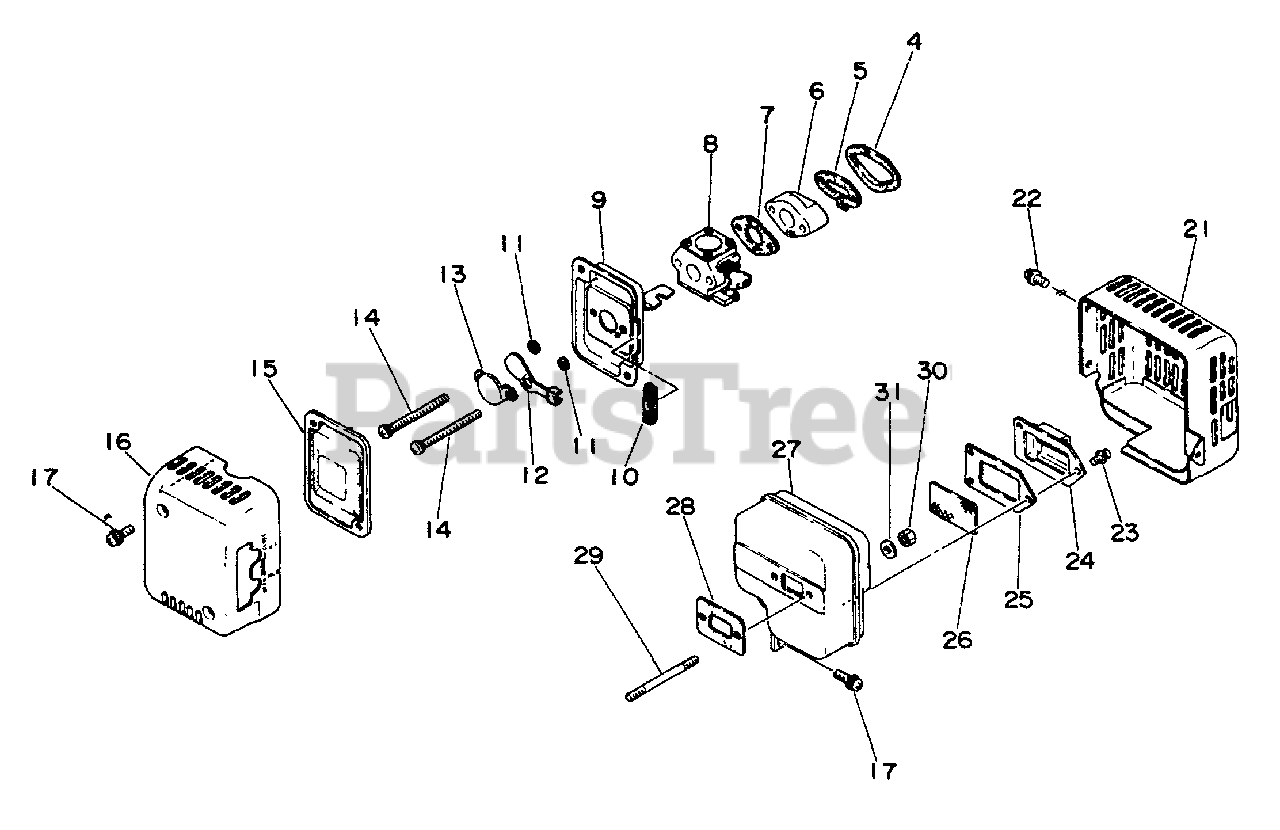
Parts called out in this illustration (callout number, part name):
5	GASKET, INTAKE
6	INSULATOR, INTAKE
7	GASKET, INTAKE
8	CARBURETOR WA-142
9	CASE, AIR FILTER
11	WASHER - 5
12	SHUTTER, CHOKE
13	PLATE, PREVENT
14	SCREW - 5X60
15	FILTER, AIR
16	COVER, AIR FILTER
17	SCREW - 5X14
17	MUFFLER ASSY
21	COVER, MUFFLER
22	SCREW - 5X10
23	SCREW - 4X8
24	GUIDE, EXHAUST
25	GASKET, EXHAUST
26	SCREEN, SPARK ARRESTOR
27	CASE, MUFFLER
28	GASKET, EXHAUST
30	LOCKNUT - 5
31	WASHER - 5
